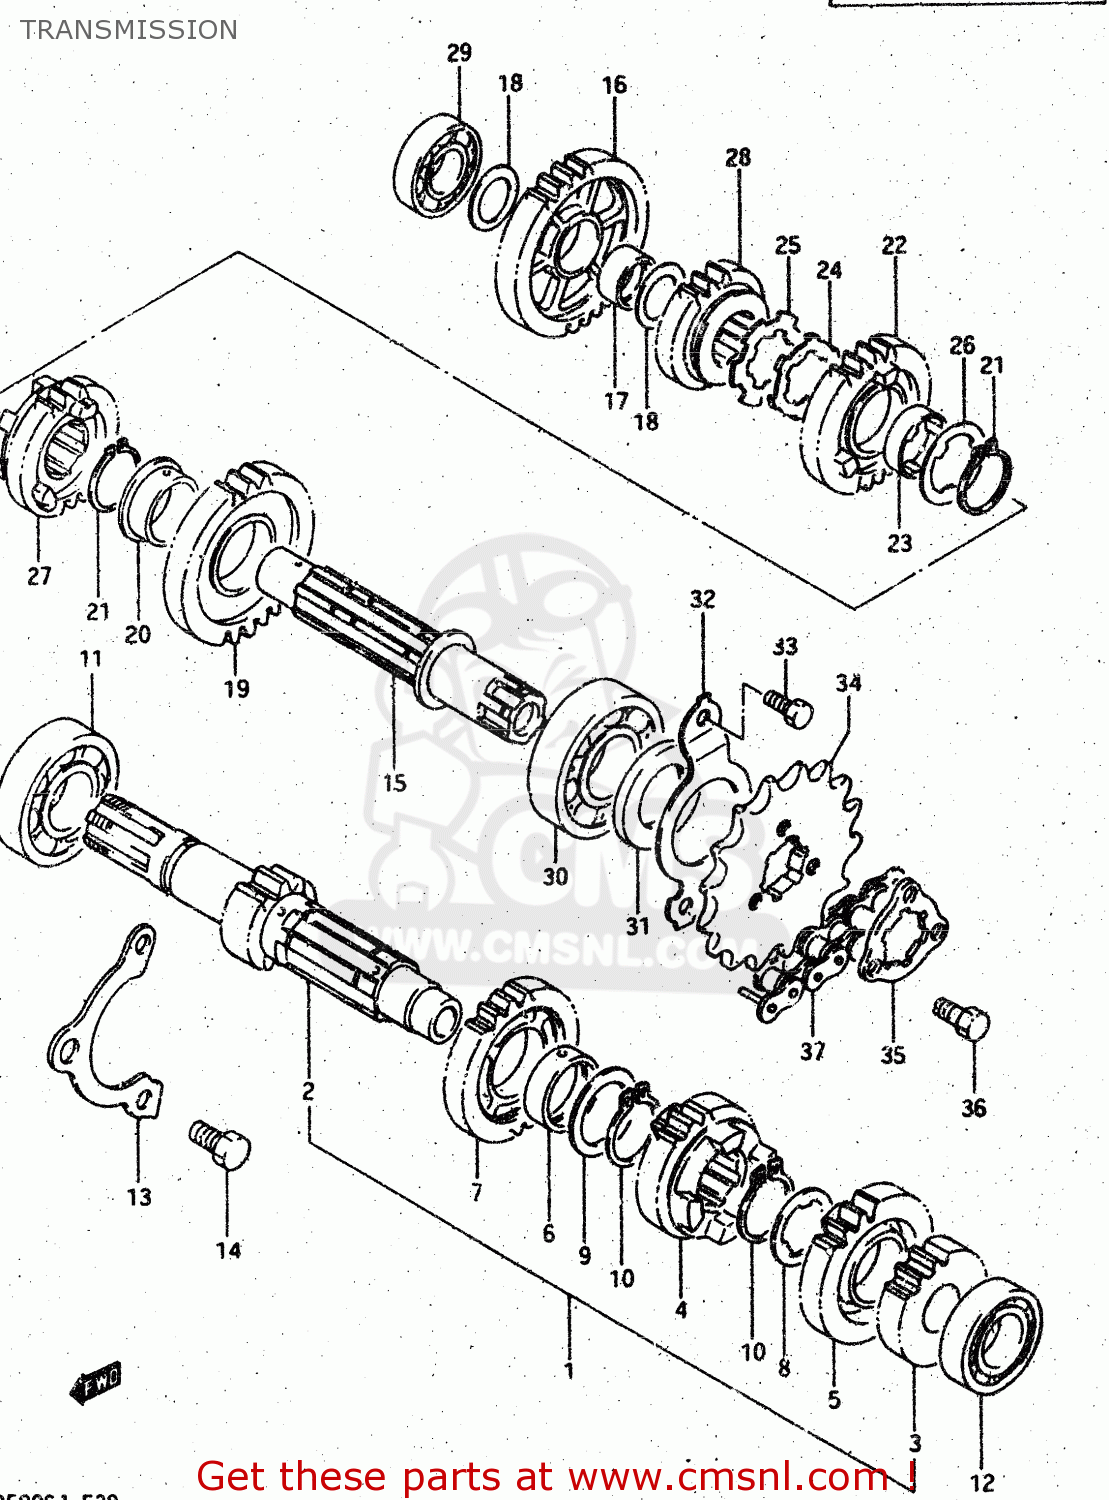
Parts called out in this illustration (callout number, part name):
1	SHAFT ASSEMBLY,COUNTER
2	SHAFT,COUNTER
3	GEAR,SECOND DRIVE
4	GEAR,THIRD/FOURTH DRIVE (NT:
5	GEAR,FOURTH DRIVE
6	BUSHING 25X29X10
7	GEAR,5TH DRIVE
8	WASHER,LOCK
9	WASHER
10	RING,SNAP
11	BEARING
12	BEARING
13	RETAINER,CNTR SHAFT BEARING
14	BOLT, 8X1.25X1
15	SHAFT,DRIVE
16	GEAR,FIRST DRIVEN
17	BUSH(20X24X13)
18	WASHER
19	GEAR,2ND DRIVEN
20	BUSH
21	RING,SNAP
22	GEAR,THIRD DRIVEN
23	BUSHING
24	WASHER
25	WASHER,LOCK
26	WASHER,LOCK
27	GEAR,FOURTH DRIVEN
28	GEAR,FIFTH DRIVEN
29	BEARING(20X42X12)
30	BEARING(25X62X17)
31	SEAL,OIL(25X45X5)
32	RETAINER,DRIVESHAFT O
33	BOLT
34	SPROCKET,ENGINE(NT:16)
35	PLATE,ENGINE SPROCKET
36	BOLT(6X13)
37	CHAIN ASSEMBLY,DRIVE
